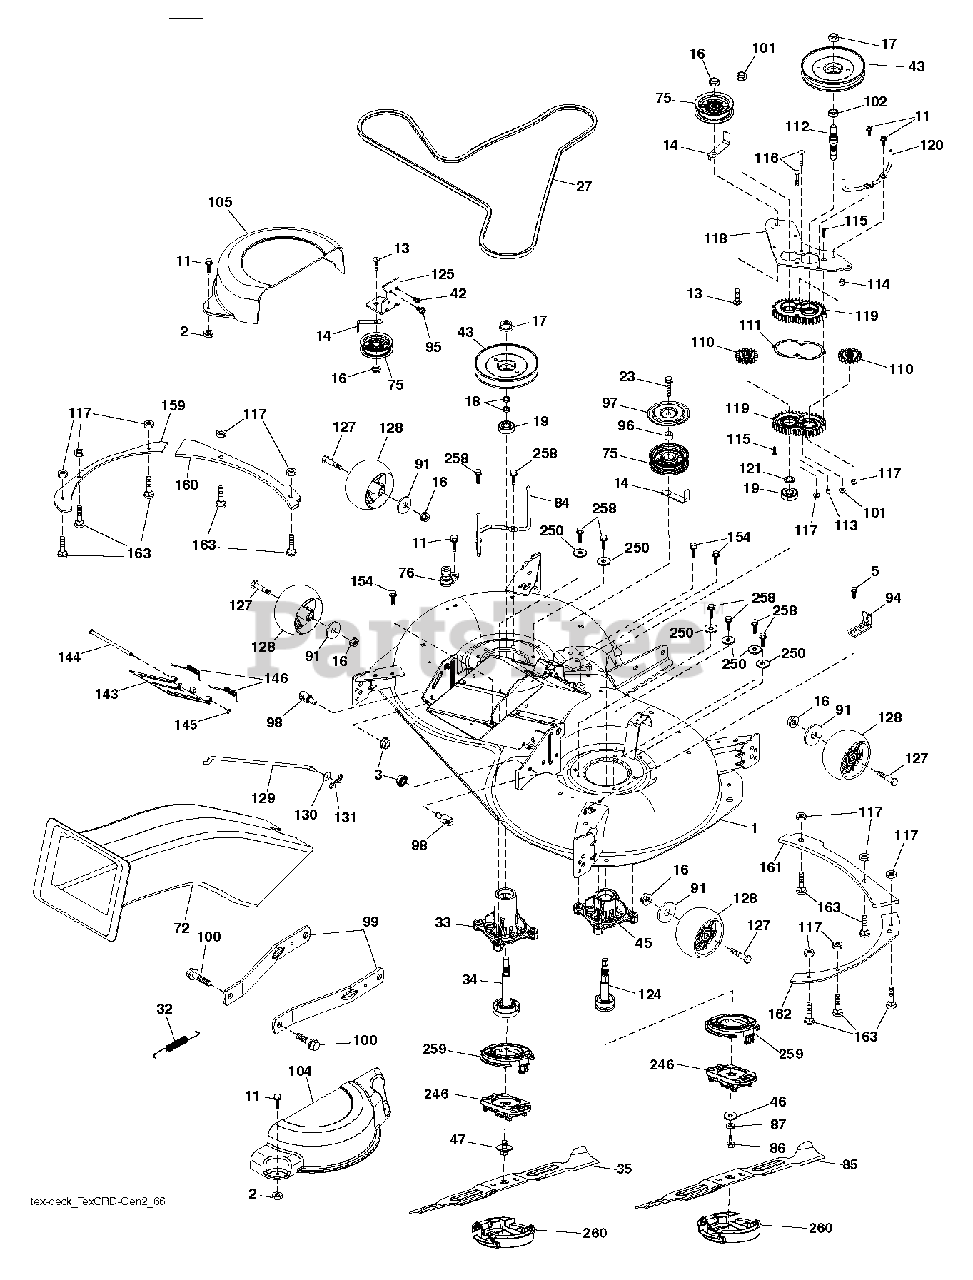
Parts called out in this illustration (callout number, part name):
1	DECK SVC 107HP.EZMUL.498
2	PALNUT 1/4
3	NUT LOCK HEX FLANGE 5/16-18
5	BOLT.5/16HEX.WHS.HD
11	SCREW.1/4-20X5/8
13	BOLT.3/8-16X1.50
14	KEEPER, BELT IDLER
16	NUT LOCK FLG 3/8-16 UNC
17	NUT.FLANGE.LOCK.TOP
18	WASHER.SPACER.MANDREL
23	SCREW LT
27	BELT BELT. ELECTRIC MOWER DRIV
32	SPRING 107CM & 97CM ELECTRIC D
33	HOUSING.MANDREL.REV.TALL.N/GRS
34	SHAFT ASM.REV.TALL.N/GREASEBL
35	BLADE.REVLTION.107CM.LHS.PT431
42	SCREW
43	PULLEY PULLEY MANDREL 5.438 PD
45	RP HOUSING.MANDREL.REV.REVS.
46	3/8 FLAT WASHER
47	SCREW.SEMS.7/16-20X1.HEX.HEAD
72	RB CHUTE 107/97 TEX GENII
75	FLAT IDLER PULLEY
76	PORT.WASHOUT
84	KEEPER KEEPER. LH MANDREL BELT
85	BLADE.REVLTION.107CM.RHS.PT431
87	LOCKWASHER
91	WASHER
94	BRKT.CLUTCH.CABLE
95	SCREW, 3/8-16X3/4
96	SPACER
97	PROTECTOR
98	STUD.FASTNER.W/ANTI-ROTATE
99	ARM.SUSPENSION.MOWER.R
100	BOLT.SHOULDER
101	NUT.CROWNLOCK.9/16 -18.UNC
102	SPACER BEARING
104	COVER.MANDREL.107.RH.GEN.2
105	COVER.MANDREL.107.LH.GEN.2
110	GEAR GEAR OUTPUT
111	GASKET GASKET GEARCASE
112	SHAFT SHAFT. CRD GEARCASE ADAP
113	PLUG PLUG OIL
114	VALVE VALVE RELIEF
115	SCREW
116	BOLT.CARIGE.SS.1/4-20X1.75GR5
117	NUT T
118	ARM ARM. CLUTCHING 107 TEX CRD
119	GEARCASE GEARCASE SUBASM
120	KEEPER KEEPER. RH MANDREL BELT
121	WASHER WASHER
124	SUB.ASM.REVERSE.THREAD.REV
125	BRACKET
127	BOLT.SHOULDER.3/8-16X3-5/8.
128	WHEEL. GUAGE RALLY
129	ROD ROD. SWAY CRD GEN II
130	WASHER
131	PIN.COTTER.5/16.BOW TI
143	COVER DOOR.107 CM CRD EZ MULCH
144	PIN PIN.HINGE
145	E-RING.5/16"
146	SPRING SPRING: EZ MULCH DOOR
154	SCREW T-30 1/4-20 X
159	REINFORCE.PLATE.LH.FT.X431
160	REINFORCE.PLATE.LHS.BOLT.431
161	REINFORCE.PLATE.RH.FRT.X431
162	REINFORCE.PLAT.RH.SD.BLT.X431
163	BOLT
246	HOLDER BLADE REVOLUTION
258	BOLT.HEX.WASHR.HED.313-18X1.19
259	CAP.REVOLUTION.UPPER
260	CAP.REVOLUTION.LOWER
